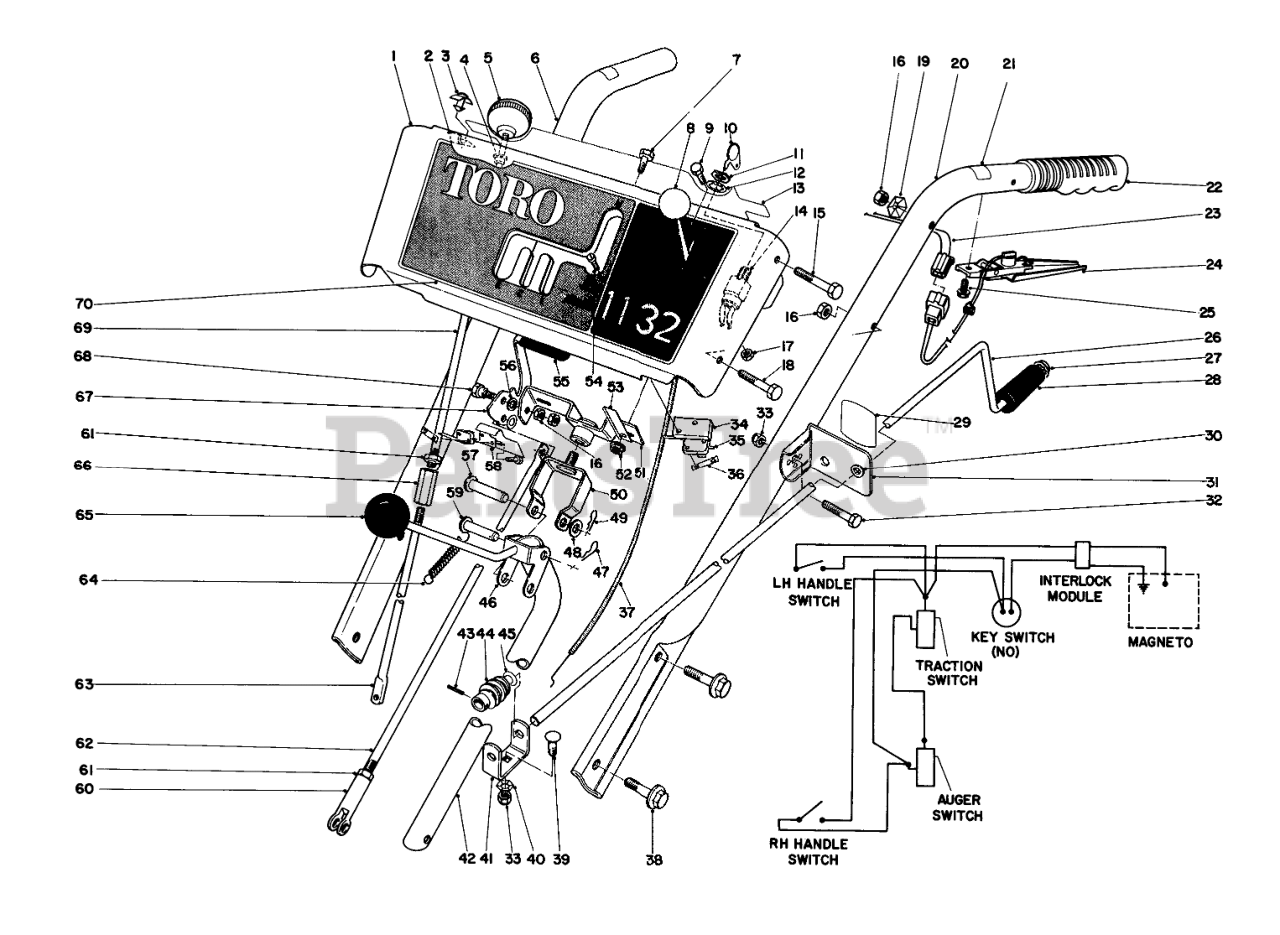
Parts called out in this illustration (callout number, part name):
1	Escutcheon Plate (Incl. Ref. #13 & 70)
2	WIRE CLAMP
3	Mounting Stud
4	NYLINER #6LI-FF TYPE 7
5	KNOB-LEVER
6	Handle Right
7	SCREW-HH
8	CONTROL KNOB
9	HEX HEAD SEMS 10-24X1/2
10	Key
11	NUT-HH
12	WASHER-TOOTH, INTERNAL
13	BACK ESCUTCH DECAL
14	Key Switch
15	SCREW-HH
16	NUT-LOCK, CONE
17	Nut
18	SCREW-HH
19	Washer
20	HANDLE LEFT
21	INTERLOCK DECAL
22	Grip Handle
23	WIRE HARNESS INTERLOC
24	INTERLOCK HDLE SWITCH
25	SCREW
26	Chute Control Rod
27	RETAINER-PUSH ON
28	GRIP-CONTROL, CHUTE
29	CHUTE DECAL
30	Bushing
31	Bracket-Chute Control Mtg. (Incl. Ref. #29 & 30)
32	SCREW-HH
33	NUT-LOCK, NI
34	SWITCH MTG PAD
35	SWITCH-MICRO
36	NUT-SPEED
37	Throttle Contrl
38	SCREW-HHF
39	BOLT-CARR
40	WASHER-LOCK
41	WORM BRACKET
42	Rod Traction Shift
43	PIN-SPRING
44	GEAR-WORM, CHUTE
45	WASHER-SPRING
46	SHIFT ROD WA
47	PIN-COTTER
48	WASHER-FLAT
49	PIN-HAIR
50	PIVOT BRKT WA
51	SWIVEL BLOCK WA
52	NUT-LOCK, HHF
53	Retainer Wire
54	SCREW-SPH
55	AUGER CLUTCH HND GRIP
56	WASHER-PLAIN
57	PIN-CLEVIS
58	SWITCH BRKT
59	PIN-CLEVIS
60	CLEVIS
61	NUT-HJ
62	DRAG LINK
63	LOWER WHL CLUTCH ROD
64	CONT ROD SPRING 0
66	WHL ROD COUPLING
67	Auger Clutch Handle
68	SCREW-SHOULDER
69	UP WHEEL CLUTCH ROD
70	ESCUTCHEON DECAL
